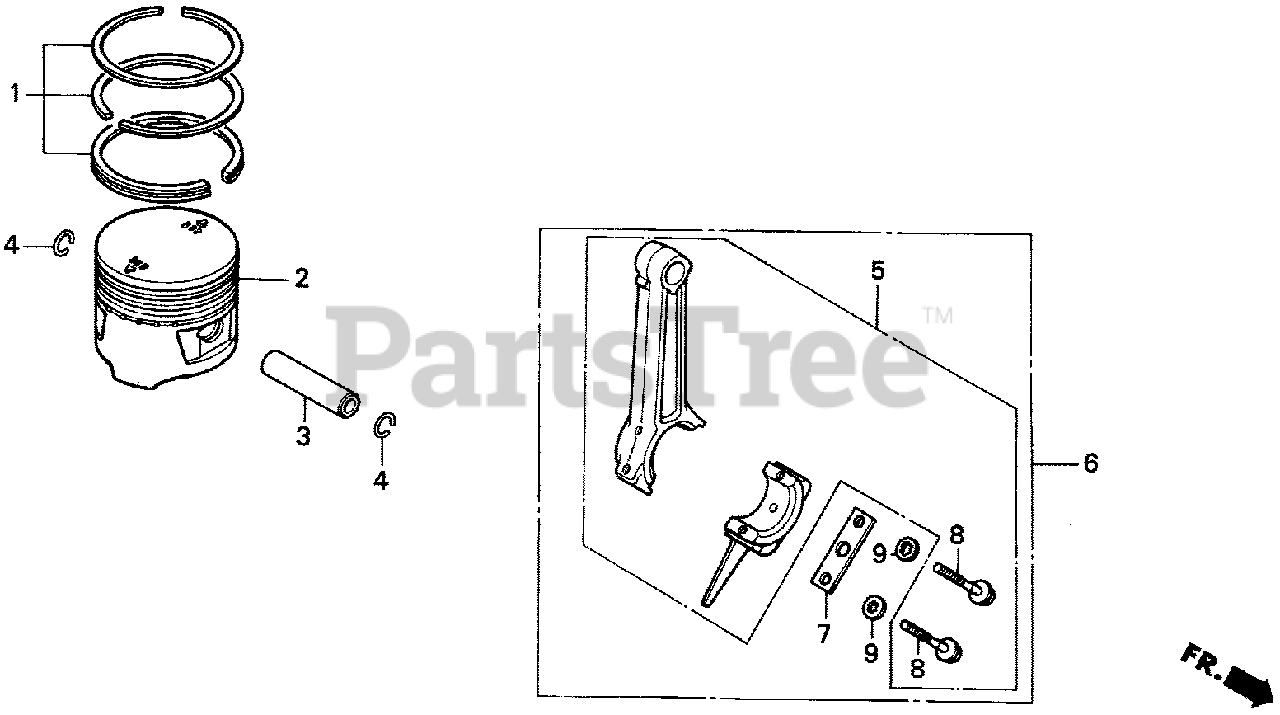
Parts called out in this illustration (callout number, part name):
1	RING SET, PISTON (STD)
1	RING SET, PISTON (OS 0.25)
1	RING SET, PISTON (OS 0.50)
1	RING SET, PISTON (0.75)
2	PISTON (STD)
2	PISTON (OS 0.25)
2	PISTON (OS 0.50)
2	PISTON (0.75)
3	PIN, PISTON
4	CLIP, PISTON PIN (10MM)
5	ROD ASSY., CONNECTING (STD)
5	ROD ASSY., CONNECTING (UNDER SIZE)
8	BOLT, CONNECTING ROD
